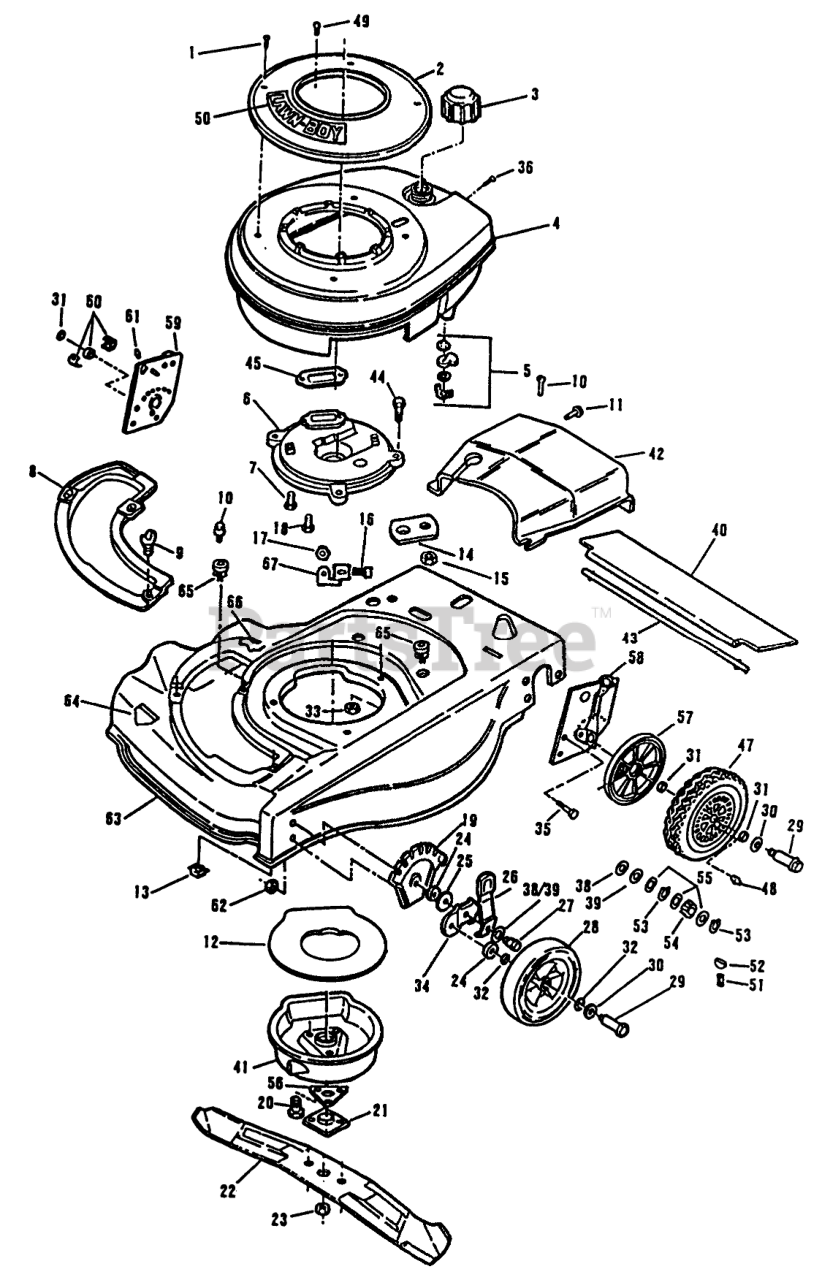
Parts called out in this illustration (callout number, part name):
1	SCREW S
2	STARTER BASE&NUTG
3	FUEL CAP & INSERT
4	Shroud-Engine
5	SHUT OFF VALVE KIT
6	PLATE,MUFFLER S
7	SCREW V
8	CoverPlate
9	WING SCREW LAWRE
10	Bolt
11	SCREW
12	BAFFLE,MUFFLER S
13	NUT-CAGE
14	BOLSTER PLATE LB
15	LOCKNUT E
16	Screw
17	LOCKNUT E
18	SCREW F
19	PLATE HGT ADJ TRO
20	SCREW
21	PLATE AND COLLAR ASM
22	21" Blade
23	NUT-BLADE
24	WASHER WROUGHT
25	WASHER
26	KNOB&SPRING FORMCO
27	BOLT
28	WHEEL&TIRE 6"
29	BOLT WHEEL
30	WASHER-PLAIN
31	WASHER
32	WASHER
33	NUT-LOCK F
34	Bracket
35	Screw
36	SCREW S
37	Screw
38	WASHER
39	WASHER
40	SHIELD-TRAILING
41	MUFFLER COVER F
42	COVER-BELT PL
43	ROD-TRAILING SHIELD
44	SCREW-HH
45	Gasket
46	NUT-LOCK F
47	WHEEL AY
48	FITTING LINCOLN
49	SCREW SEMS SM
50	APPLIQUE
51	SPRING
52	KEY
53	RET RING
54	PINION BROCKWAY
55	SPACER/GR ALGHNY
56	SUPPORT F
57	W/COVER WHITE PL
58	HEIGHT ADJ. AY.
59	HEIGHT ADJ. AY.
60	REAR AXLE BEARING
61	FITTING LINCOLN
62	NUT
63	HSG AY-21"
64	Decal
65	Grommet
66	DECAL SGI
67	BRACKET ARGO
